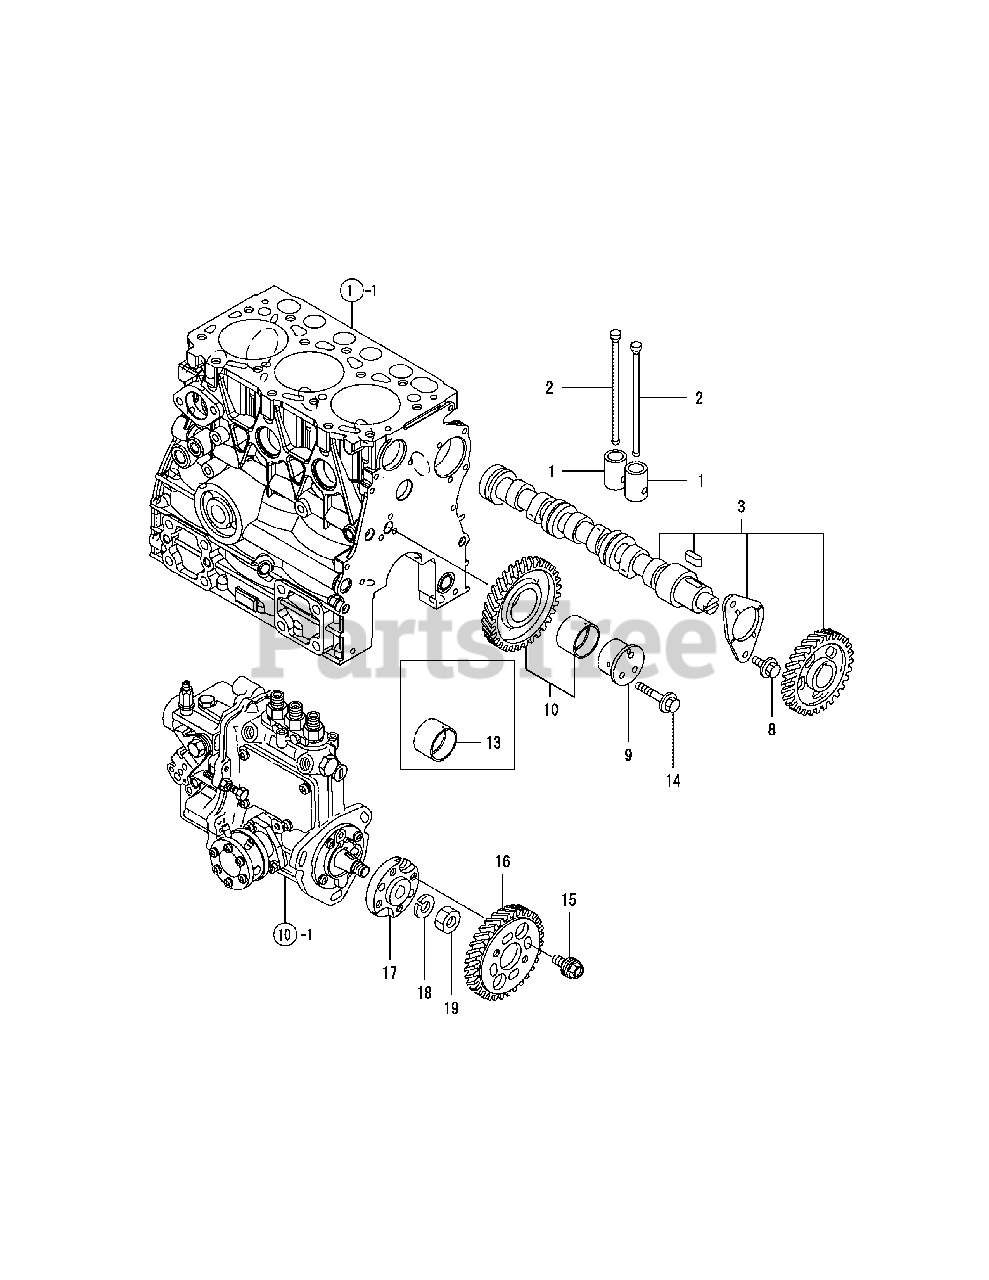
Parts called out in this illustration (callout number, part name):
3	Camshaft Assembly
8	Bolt, M 6 x 12 Plated
9	Shaft, Idle Gear
10	Gear Assembly, Idle
13	Bush, Idle Gear
14	Bolt, M 6 x 35 Plated
18	Spring Washer 12
